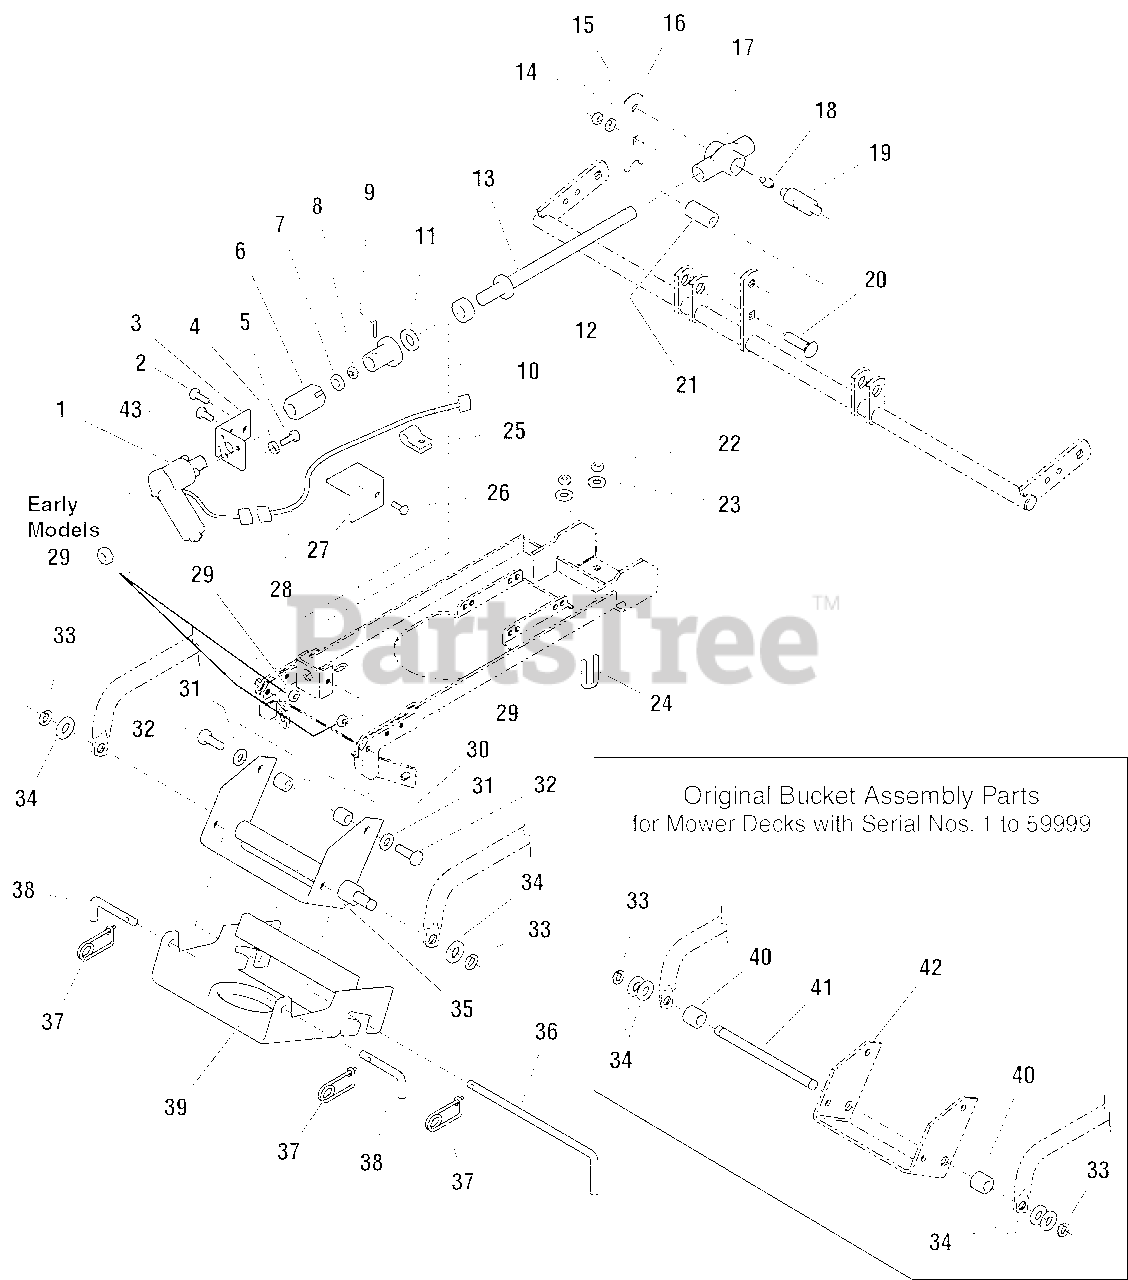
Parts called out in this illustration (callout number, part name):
1	MOTOR, Electric Cutting Height Adjust
2	CAPSCREW, Hex Washer Head, Taptite, 5/16-18 x 1, Black
3	BRACKET, Motor Mounting
4	LOCKWASHER, 1/4
5	CAPSCREW, Hex Head, 1/4-20 x 3/4
6	ADAPTER, Motor
7	WASHER, Plain, 1/4
8	NUT, Hex Centerlock, 1/4-20
9	ROLL PIN, 3/16 x 1 3/4
11	WASHER, Nylon
12	BEARING, Thrust
13	SHAFT ASSEMBLY
14	NUT, Hex, 1/2-13
15	LOCKWASHER, 1/2
18	FITTING, Lube
20	CARRIAGE BOLT, 1/2-13 x 2 1/2
22	NUT, Hex Nylon Lock, 5/16-18
23	WASHER, Plain, 5/16
24	U-BOLT, Clamp
26	CAPSCREW, Hex Head, Taptite, 5/16-18 x 1/2
27	COVER, Motor
28	HARNESS, Mower lift
29	NUT, Top Lock Spiral Flange, 3/8-16 (Later Models)
29	NUT, Hex Nylon lock, 3/8-16 (Early Models)
31	WASHER, Plain, 3/8
32	CAPSCREW, Hex Head, 3/8-16 x 1 1/2
33	RETAINING RING, 5/8
34	WASHER, 5/8
35	HITCH & SHAFT ASSEMBLY,
37	PIN, Safety
39	HITCH & BAR ASSEMBLY, Mower Front Hitch
41	SHAFT, Hitch
42	BRACKET, Front Mower Hitch
43	CAPSCREW, Hex Washer Head Taptite, 5/16-18 x 3/4, Black
